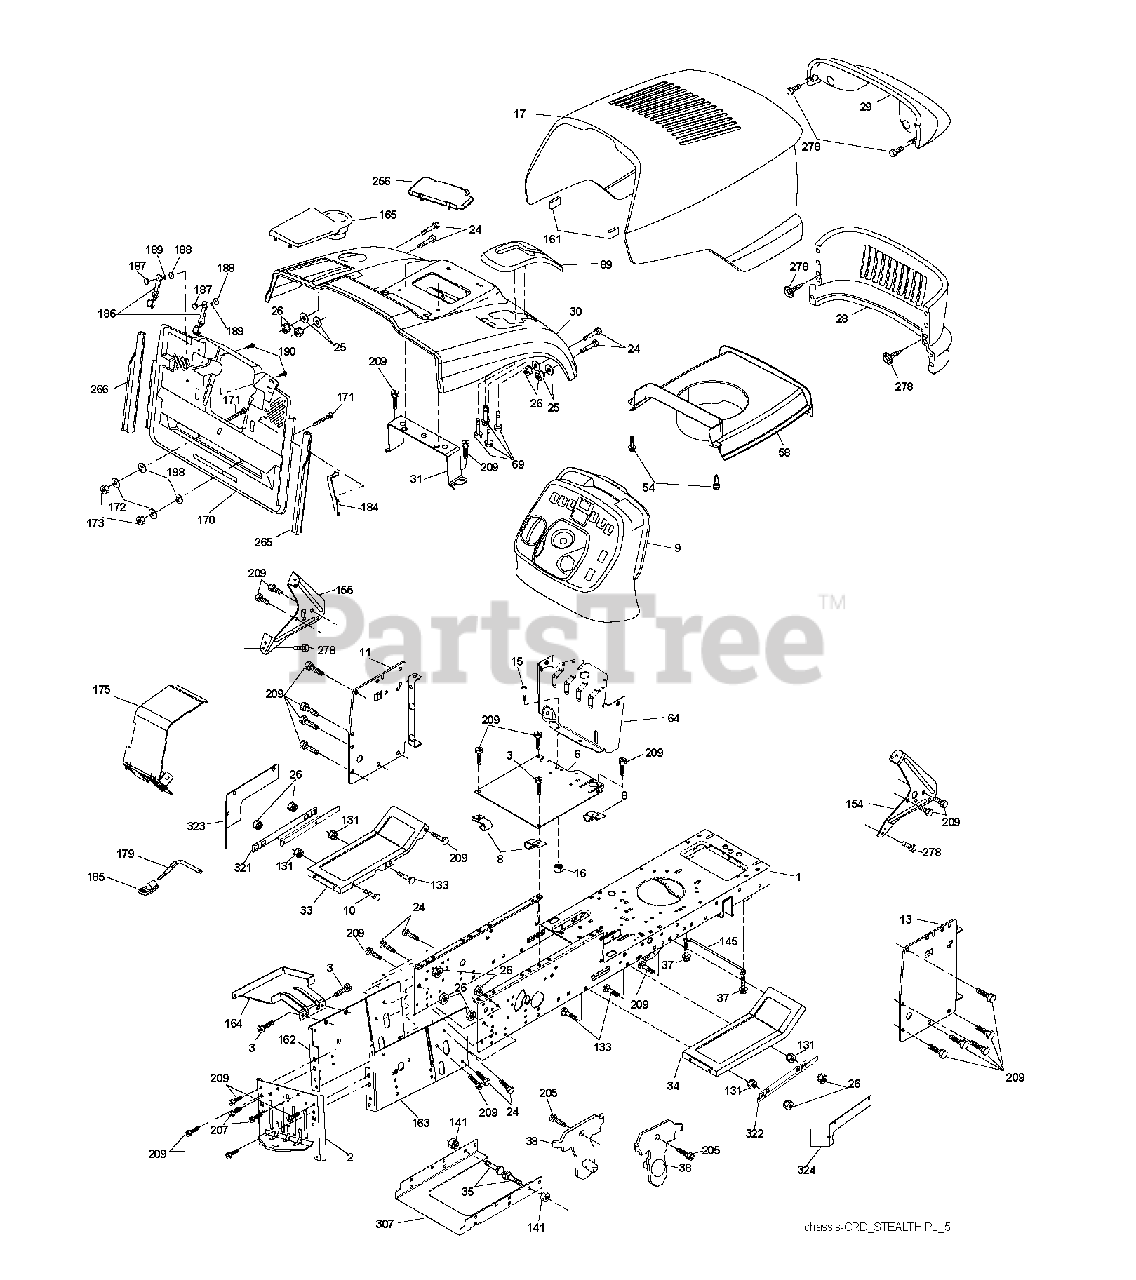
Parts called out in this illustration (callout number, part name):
1	CHASSIS
3	SCREW 3/8-16X3/4
8	CLIP,INSULATOR
10	BOLT.3/8-14X1.25
13	PANEL DASH RH
16	NUT
25	WASHER
26	NUT
31	BRACKET SUPPORT FENDER
54	SCREW.WSHD.HEX10-32X5/8
58	DUCT HOOD
69	SCREW.HI-LO.CONSOLE
131	NUT.HEX.3/8-16UNC
141	NUT LOCK FLG 3/8-16 UNC
145	ROD.PIVOT.HOOD
161	EXTRUSION BUMPER
164	SUPPORT
171	BOLT
172	WASHER
186	LATCH ASSY
187	WELDNUT
189	LOCKWASHER
207	SCREW, 5/16-18 X 1/2
209	SCREW, 3/8-16X3/4
278	SCREW.#10 X 0.750.BOS THREAD
